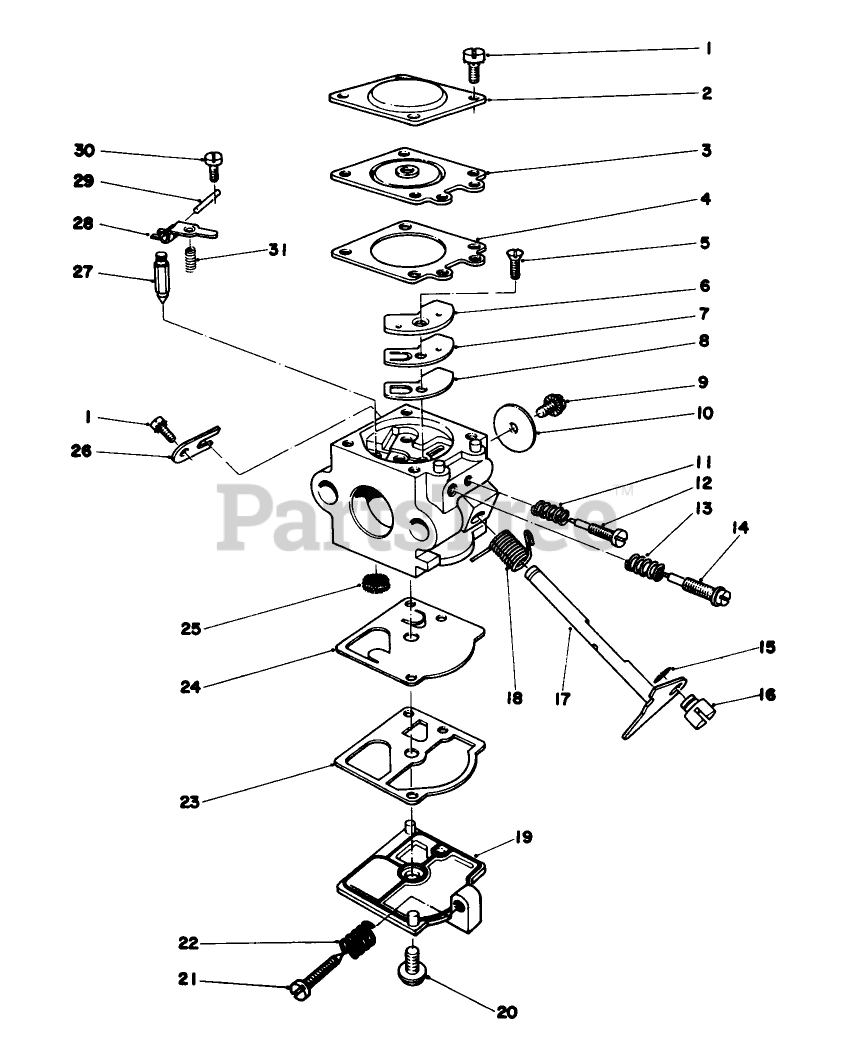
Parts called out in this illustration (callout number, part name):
1	Screw
2	Cover, Diaphragm
3	METERING DIAPHRAGM
4	Gasket, Diaphragm
5	Screw-Circuit Plate
6	Plate, Circuit
7	Diaphragm Circuit Plate
8	Gasket-Circuit Plate
9	Screw
10	Valve Throttle
11	Spring, Needle
12	Idle Needle
13	Spring, HS Needle
14	Needle, High Speed
16	Swivel
17	THROTTLE SHAFT ASM
18	Spring-Throttle Lever
19	Cover, Fuel Pump
20	Screw
21	Screw, Idle Adjust
22	Spring, Idle Screw
23	PUMP GASKET
24	Diaphragm Fuel Pump
25	Screen Inlet
26	Clip Throttle Shaft
27	INLET NEEDLE VALVE
28	Lever Metering
29	Metering Lever Pin
30	Screw-Metering Pin
31	Spring, Lever
